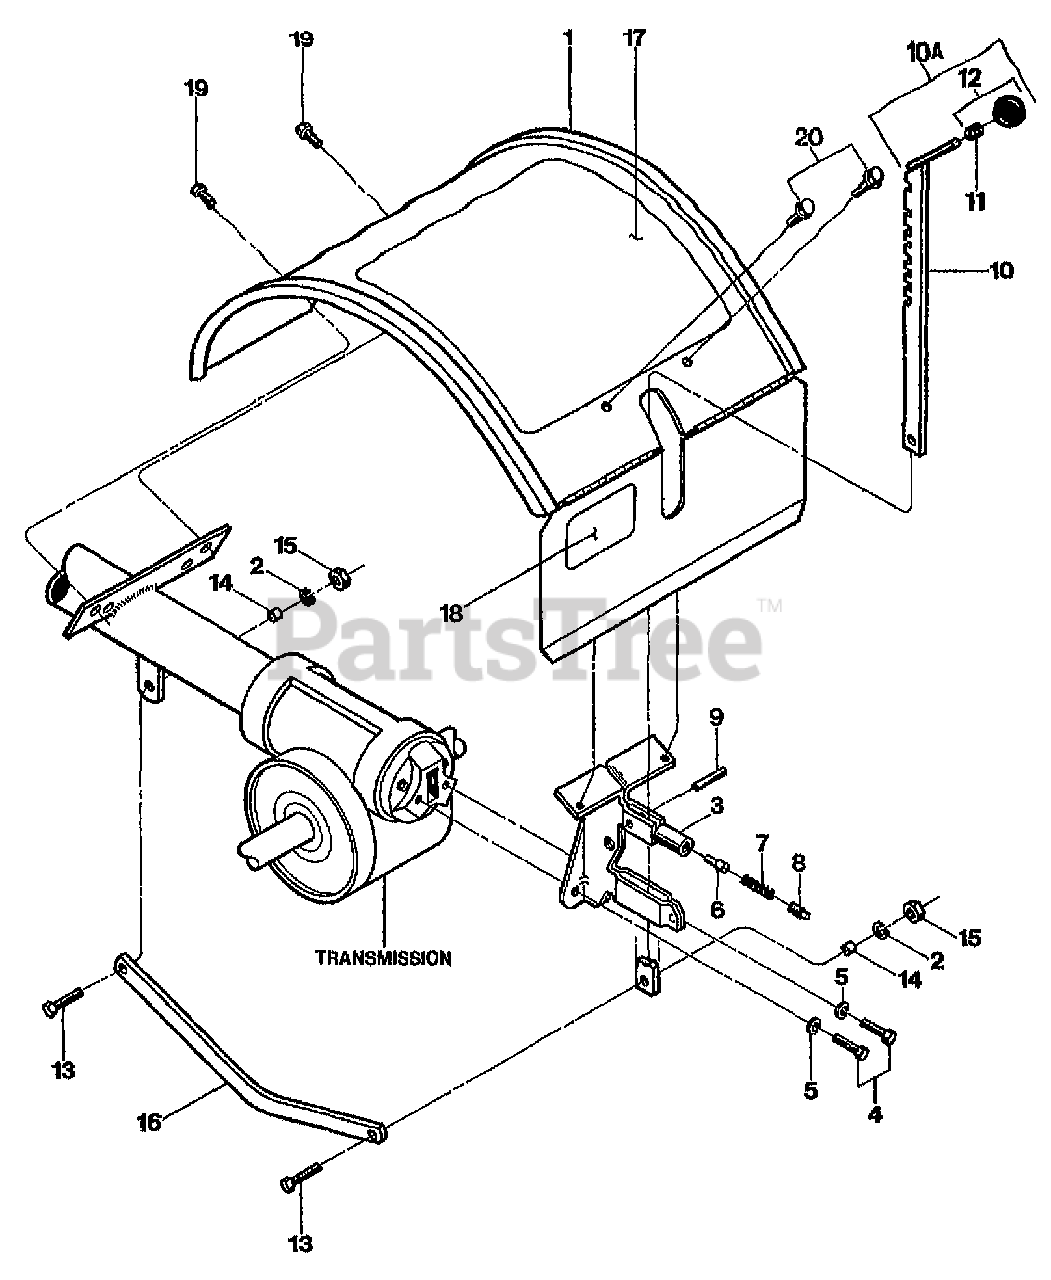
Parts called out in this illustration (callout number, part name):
1	HOOD W/DECALS P/J (Tine cover w/ hinged flap; Inc. 17 & 18.)
2	WASHER-LK .375 @ DEPL
3	KIT-REAR HOOD BRKT (Hood & depth reg., Inc 9)
4	SCR-HHC 5/16-18X.75 GR 5 ZP (Bracket to rear bearing cap.)
5	WASHER-LK .312 ZP
6	PLUNGER (Depth reg. locking.)
7	SPRING .406 X 1.25 (Depth reg. plunger.)
8	PLUG-PIPE 1/4 NPT
9	PIN-ROLL .25 X 1 (Spiral)
10	BAR ASSEMBLY (Not available separately, see #10A)
10A	DEPTH REGULATOR W/KNOB (depth adj.; Inc. 10- 12)
11	RING-TOLERANCE .5325 ID
12	KNOB-CONTROL (Depth reg. Inc. #11)
13	SCR-HH 3/8-16X1.25
14	BUSHING-.5X.375X.3 (Spacer, Drag Bar)
15	NUT-HEX 3/8-16 ZP
16	DRAG BAR-BENT (Depth reg.)
17	DECAL-HOOD INST
18	DECAL-TB JR LOGO
19	SCR-HWH 5/16-18 X .5 STH
20	SCR-HWH 1/4-20 X .5 STH
